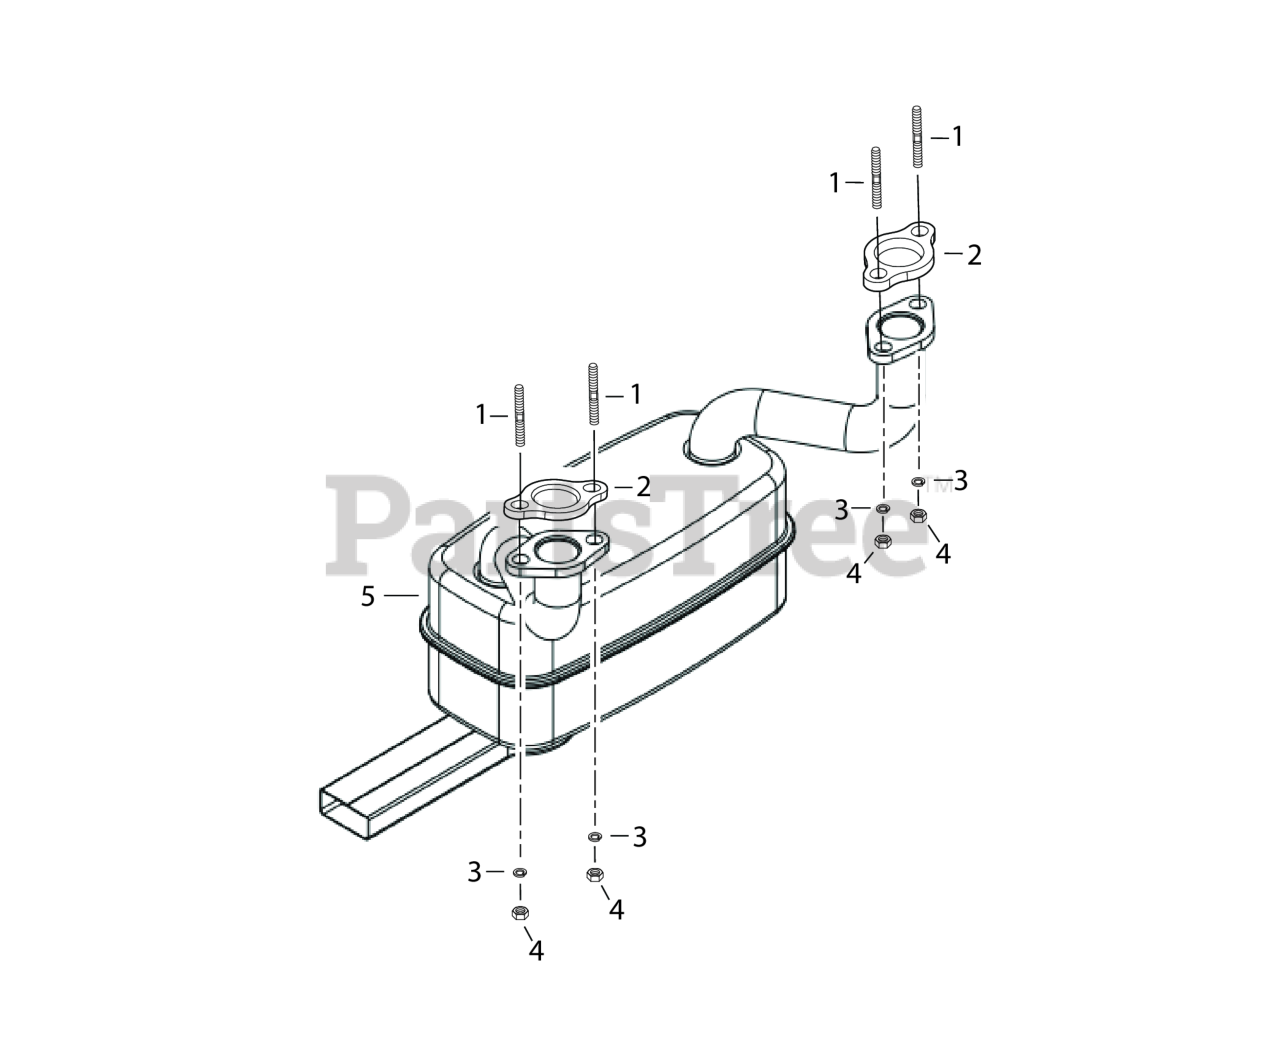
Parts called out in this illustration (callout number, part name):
1	Stud, Exhaust
2	Gasket, Exhaust
3	Washer, Lock
5	Muffler, Scag 27SR
